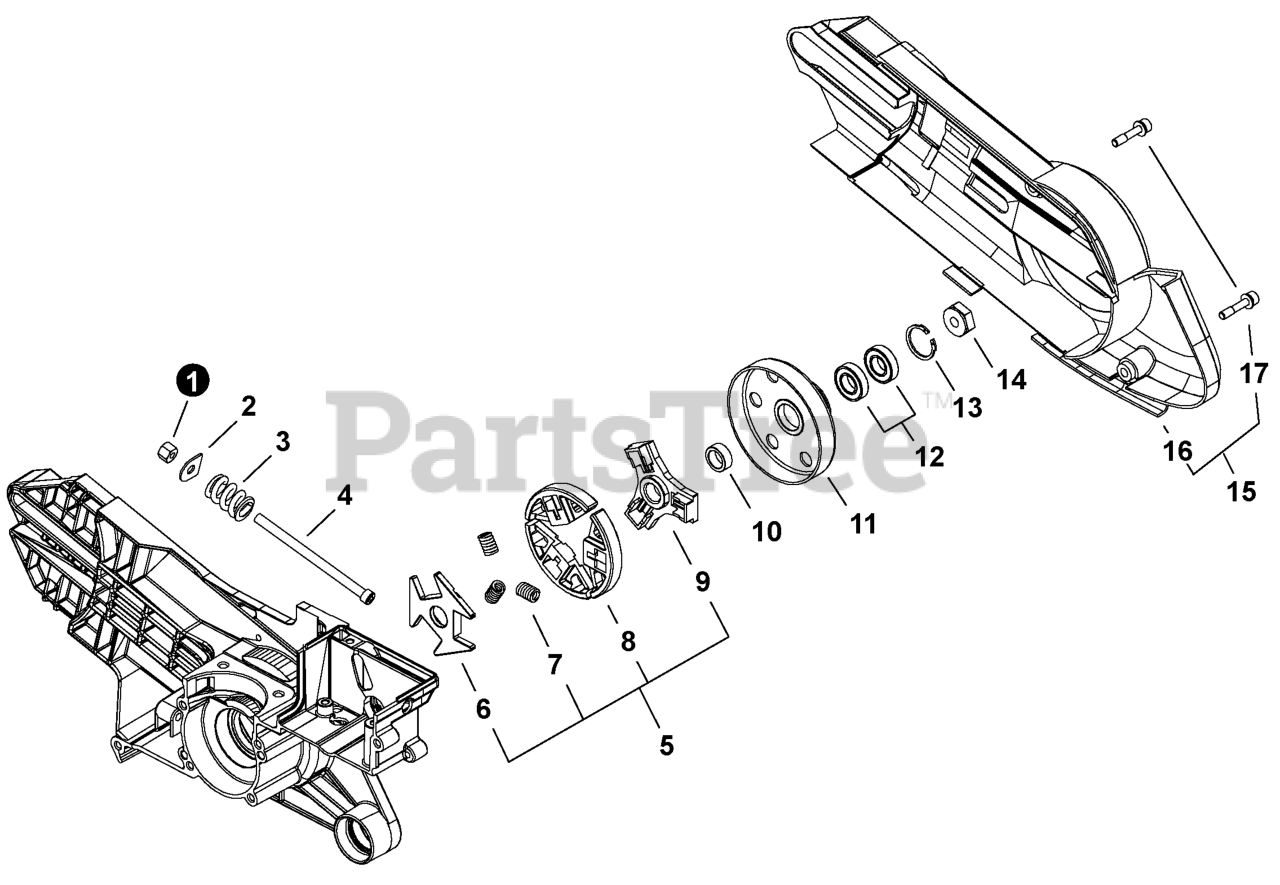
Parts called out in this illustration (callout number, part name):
3	SPRING, COIL
5	CLUTCH ASSY
6	BOSS, CLUTCH B
7	SPRING, CLUTCH
8	CLUTCH SHOE SET
9	BOSS, CLUTCH B
10	COLLAR 12
11	DRUM, CLUTCH
12	BEARING, BALL
13	RING, SNAP
15	KIT, CUTTER ARM COVER
16	COVER, CUTTER ARM
17	BOLT 5
